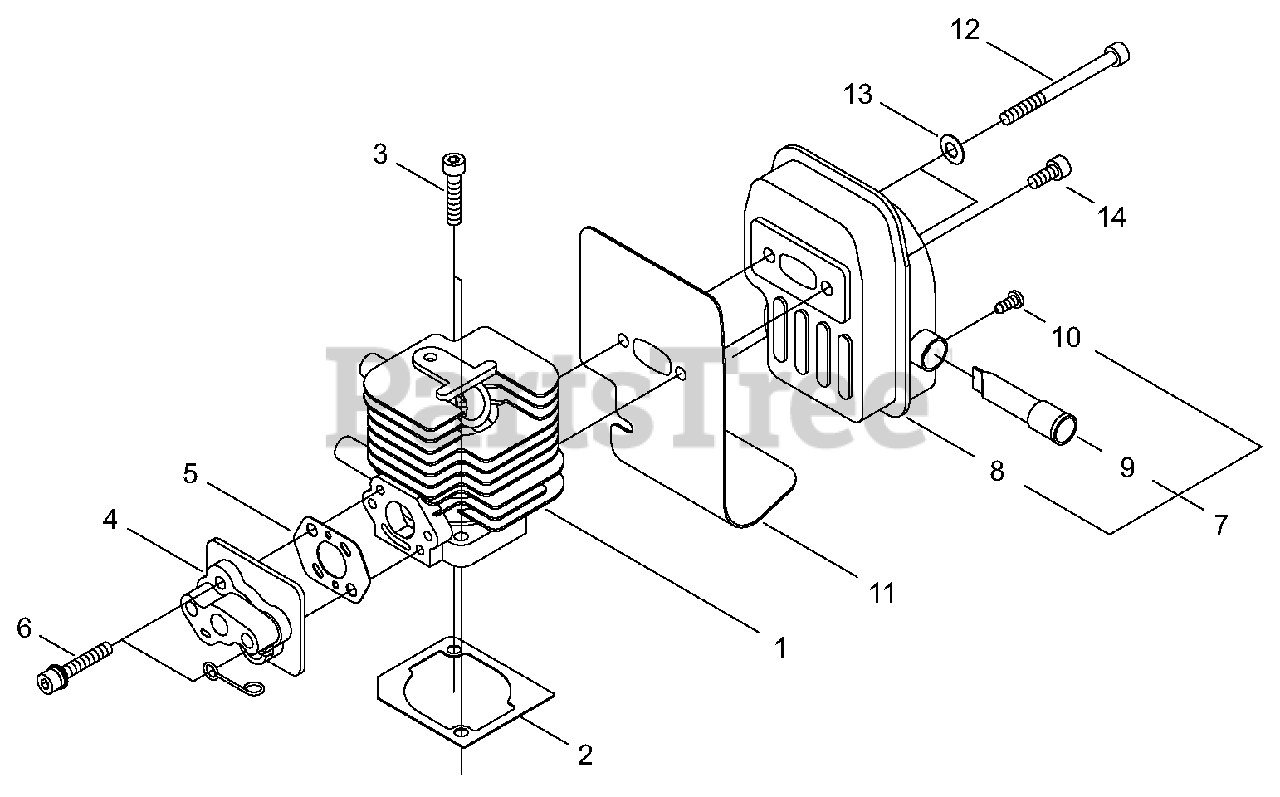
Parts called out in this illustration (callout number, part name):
1	CYLINDER
2	GASKET, CYLINDER
3	BOLT 5×25
4	INSULATOR, INTAKE
5	GASKET, INTAKE
6	BOLT M5×30
7	MUFFLER ASSY
8	MUFFLER
9	SCREEN, SPARK ARRESTER
10	SCREW, TAPPING 3×6
11	HEAT SHIELD, EXHAUST
12	BOLT M5×50
13	WASHER, FLAT 5.5×10×0.8
14	BOLT 5×12
